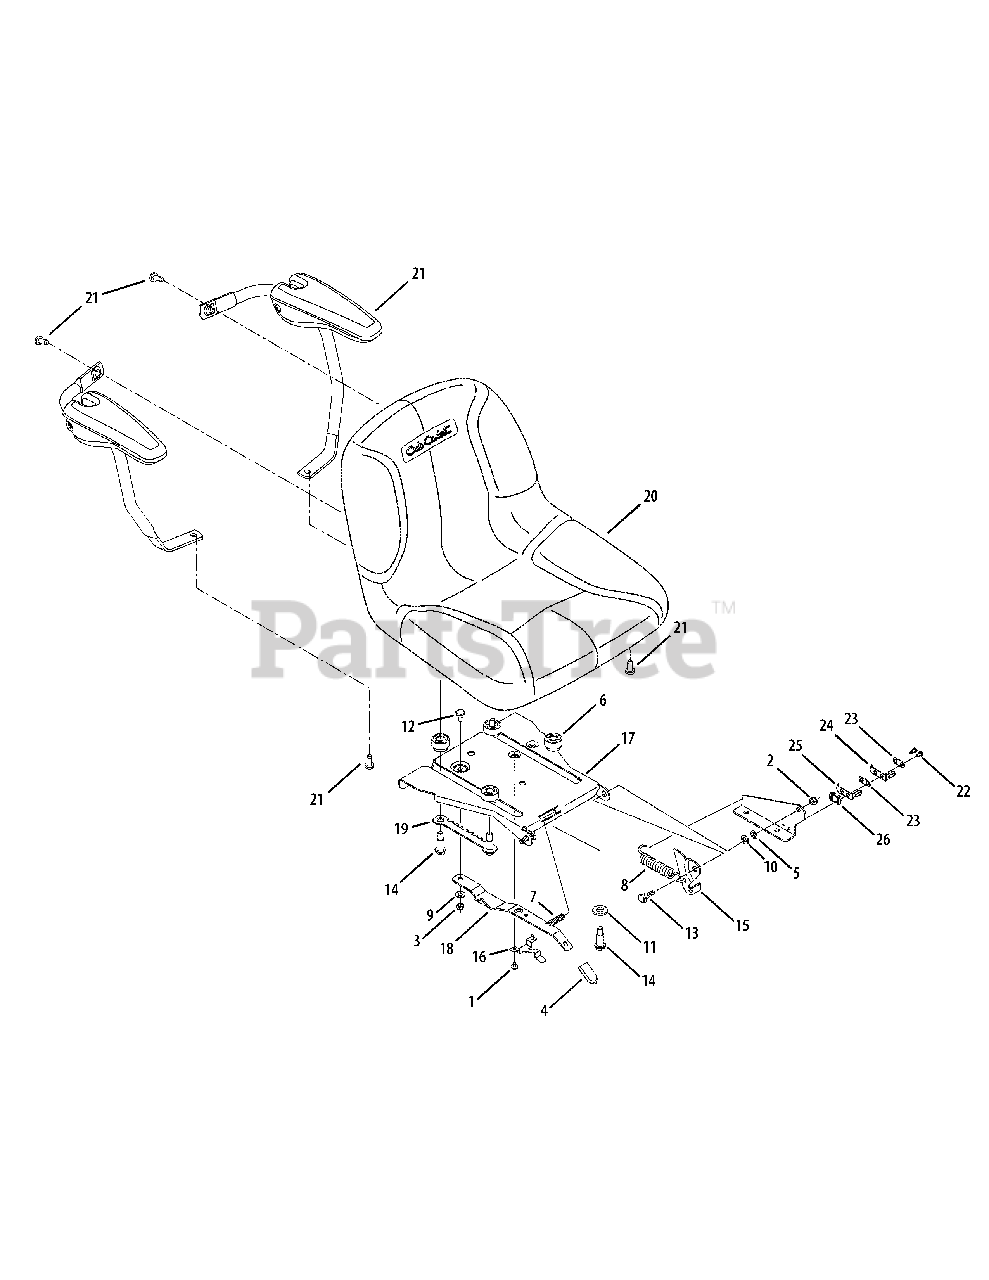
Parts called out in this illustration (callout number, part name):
1	Screw, #10-16, 0.375
2	Nut, Nylon Lock, 5/16-18, Gr5
3	Nut, Nylon Lock, 1/4-20 GrF
4	Grip, Seat, Adjustment
5	Nut, Speed, .3125 ID
6	Spacer, Seat, Adjustment
7	Spring, Compression .41 x 1.50
8	Spring, Extension, .80 Dia x 4.6
9	Washer, Flat, .344 x ..620 x .033
10	Washer, Flat, .340 x .872 x .060
11	Washer, Flat, .531 x 1.062 x .134
12	Screw, Shlder, .340 x .285, 1/4-20
13	Shoulder, Screw .437 x .286 Lg
14	Screw, Shoulder, .50 x.925, 3/8-16
15	LH Bracket, Seat Lift
16	Stop, Seat, Adjustment
19	Selector, Seat, Adjustment
20	Seat, Cub Cadet, High Back
21	Arm Rest Kit
22	Screw, #8-18 x .50
23	Plate, Insulator
24	Spring Switch, Outer
25	Spring Switch, Inner
26	Plate, Insulator Boss
